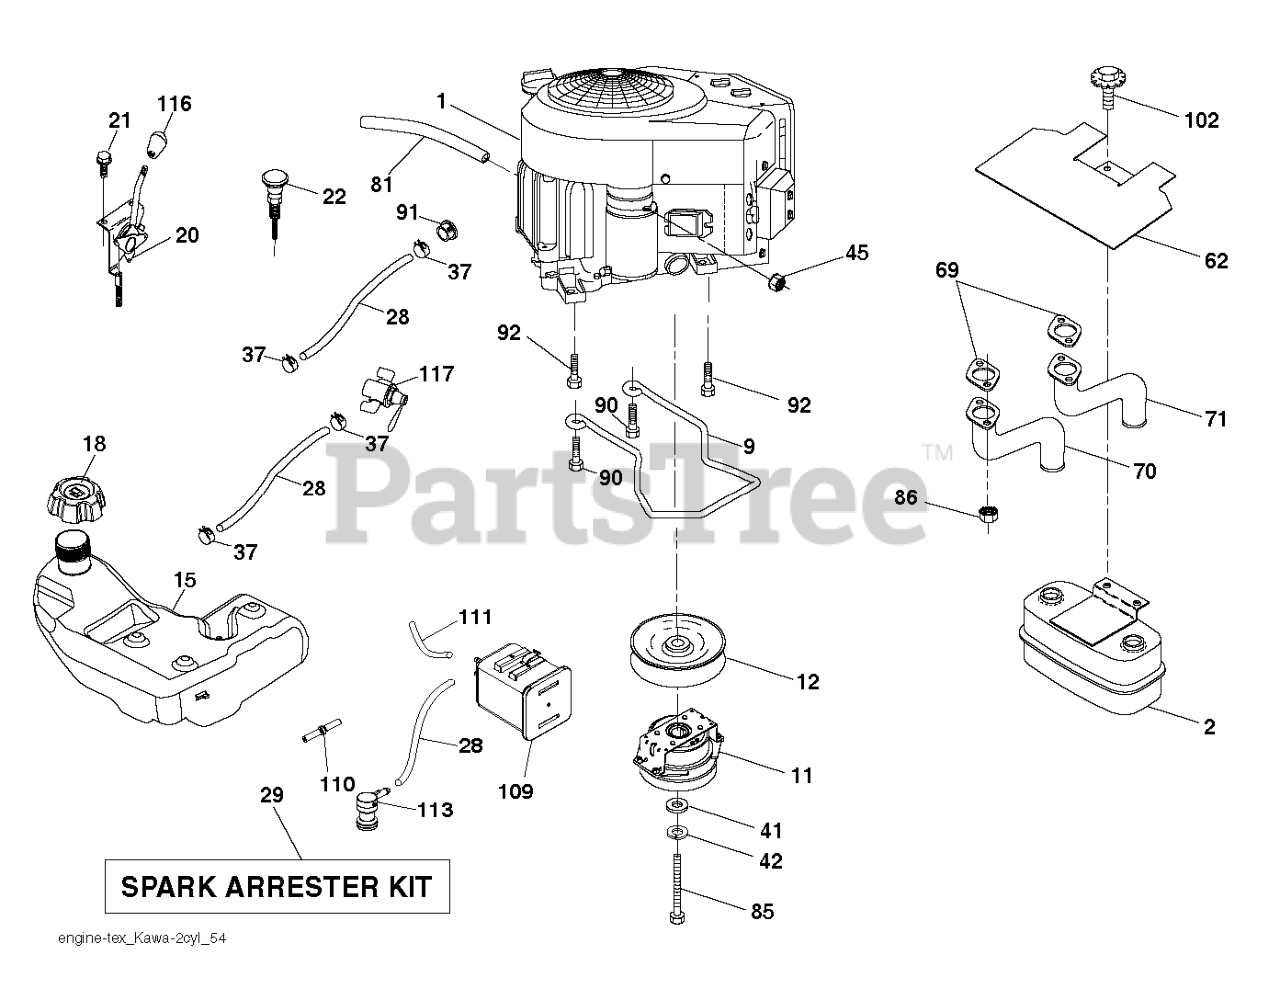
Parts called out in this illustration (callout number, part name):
2	MUFFLER.ASM.TWIN.MNTG.BRACKET
9	KEEPER.BELT.ENG.4.25"2.BLT.431
11	CLUTCH.OGURA.5.0PD.GT1.5A-EH01
12	PULLEY ENGINE
15	TANK.ASM.FUEL.4R.GAL.CARB.17
18	CAP ASSY FUEL 3" GRAY
18	FUEL CAP
20	CONTROL.THROTTLE.PRO.
21	SCREW.#10 X 0.750.BOS
22	CONTROL, CHOKE
28	LINE.FUEL.64"REAR.EMIS
29	KIT.SPARK ARRESTOR 794945 B&S
37	HOSE CLAMP
42	LOCKWASHER
45	NUT
62	SHIELD.HEAT.MUFFLER
70	TUBE.EXHAUST.LH.FR961/FR730
71	TUBE.EXHAUST.RH.FR961/FR730
81	TUBE, DRAIN OIL ASM.
85	BOLT.HEX.7/16-20X3.GR5.YELLOW
86	NUT.HEX.FLANGE.TOPLOCK
90	SCREW 3/8-16X1
91	BUSHING.1.375OD
92	SCREW 3/8-16X1
102	SCREW
109	CANNISTER, CARBON
110	VALVE.ASM.ANTI-SLOSH
111	RP PURGE LINE
113	VALVE.SLANT.CARTRDG.90 DEG.TEX
116	KNOB - SHIFT
117	VALVE FUEL RESERVE
